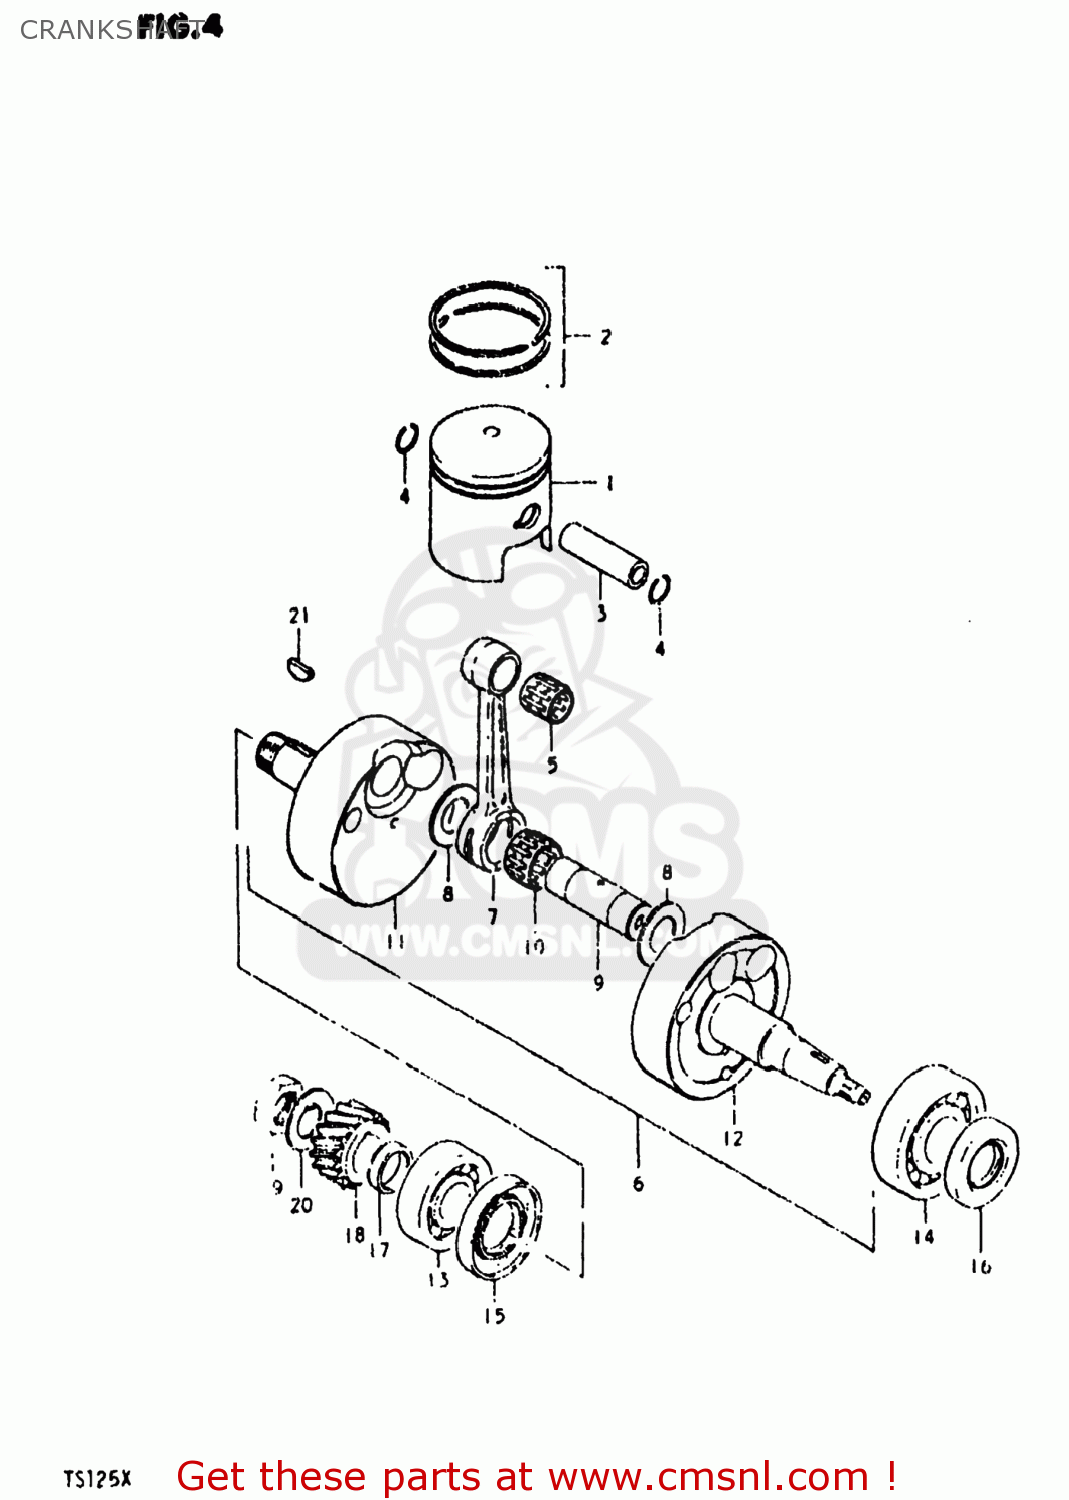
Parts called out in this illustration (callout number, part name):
1	PISTON
2	RING SET,PISTON
3	PIN,PISTON
4	RING,SNAP 14MM
5	BEARING
6	CRANKSHAFT ASSEMBLY
7	CONNECTING ROD
8	WASHER(19X32X1)
9	PIN,CRANK
10	BEARING(19X25X16)
11	CRANKSHAFT,R
12	CRANKSHAFT,LEFT
13	BEARING
14	BEARING(25X62X17)
15	SEAL,OIL(26X52X8)
16	SEAL,OIL(25X44X7)
17	SPACER(20X28X7)
18	GEAR,PRIMARY DRIVE
19	NUT
20	WASHER
21	KEY
